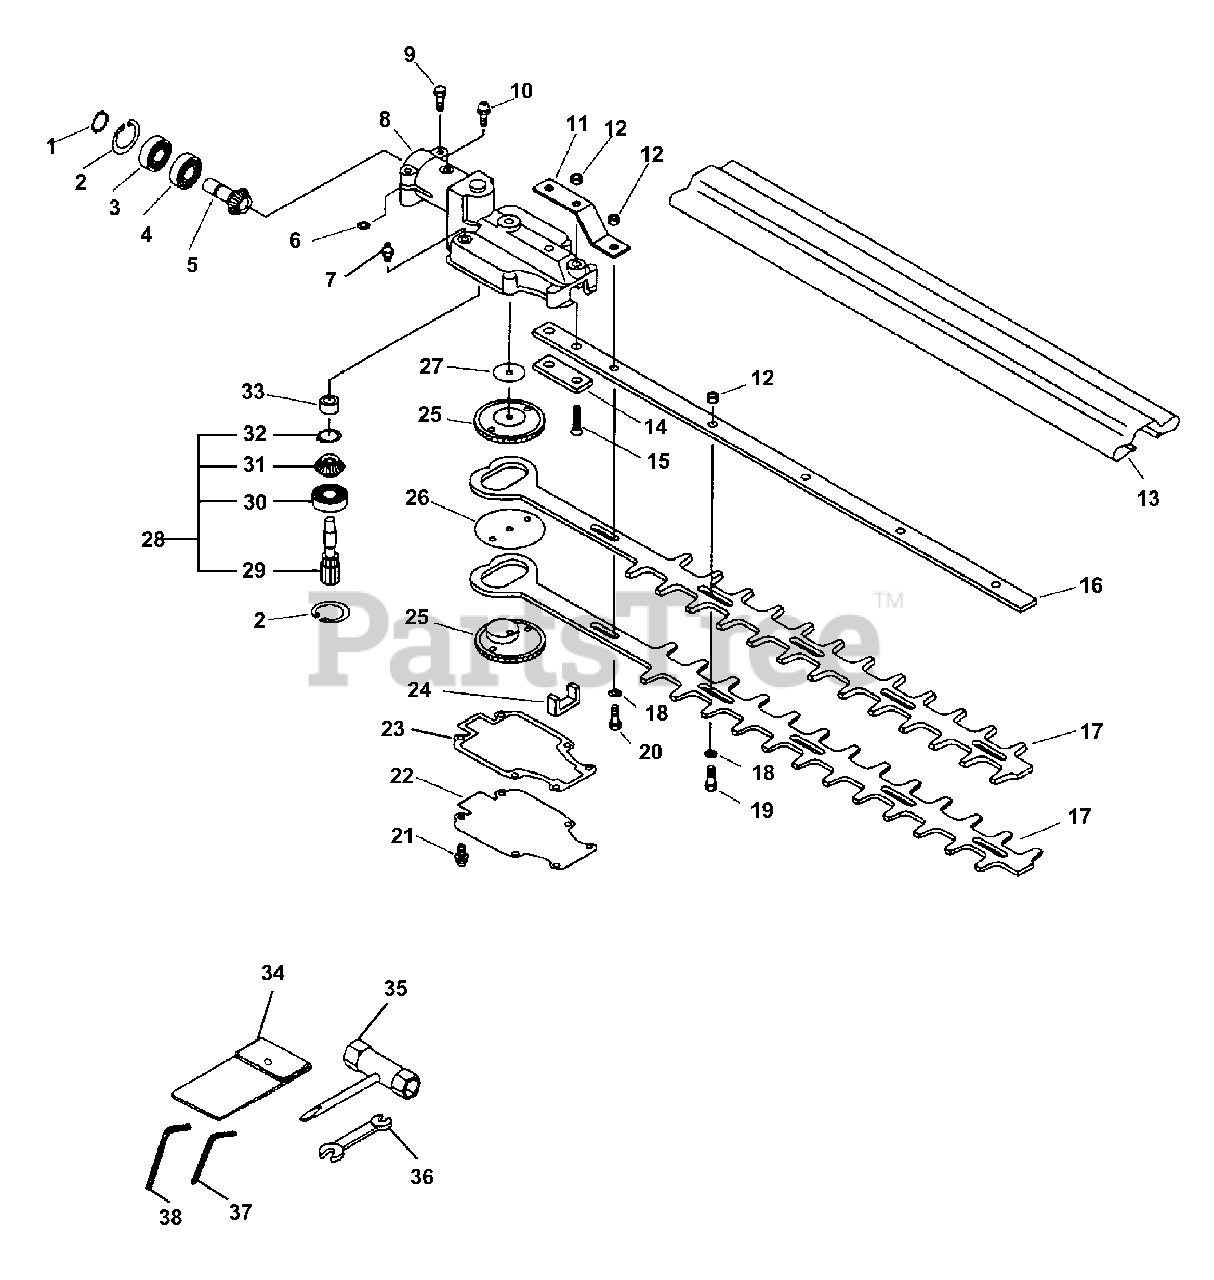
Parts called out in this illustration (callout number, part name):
1	RING, SNAP Ø12
2	RING, RETAINING Ø24
3	BEARING, BALL 6901Z
4	BEARING, BALL 6901
5	GEAR
5	GEAR, BEVEL
7	FITTING, GREASE
8	CASE, GEAR - UPPER
9	BOLT 5×28
10	BOLT 5×12
11	BRACKET, BLADE
13	SCABBARD 20"
14	SPACER
15	SCREW 6×35
16	BAR, FRAME
17	CUTTER
18	WASHER 6.5×15.5×0.6
20	BOLT 6×20
21	BOLT 4×12
22	LID, GEAR CASE
23	GASKET, GEAR CASE
24	PACKING, FELT
25	GEAR, SPUR
26	WASHER 6.7×54×0.38
27	WASHER 6.5×30×0.2
28	SPUR GEAR ASSY
29	GEAR, PINION
30	BEARING, BALL 6901
31	GEAR, BEVEL - DRIVEN
32	RING, RETAINING
33	BEARING, NEEDLE
34	BAG, TOOL
35	T-WRENCH 17x-19 L200
36	SPANNER 8×10
37	WRENCH, ALLEN 3 MM
38	WRENCH, ALLEN 4 MM
